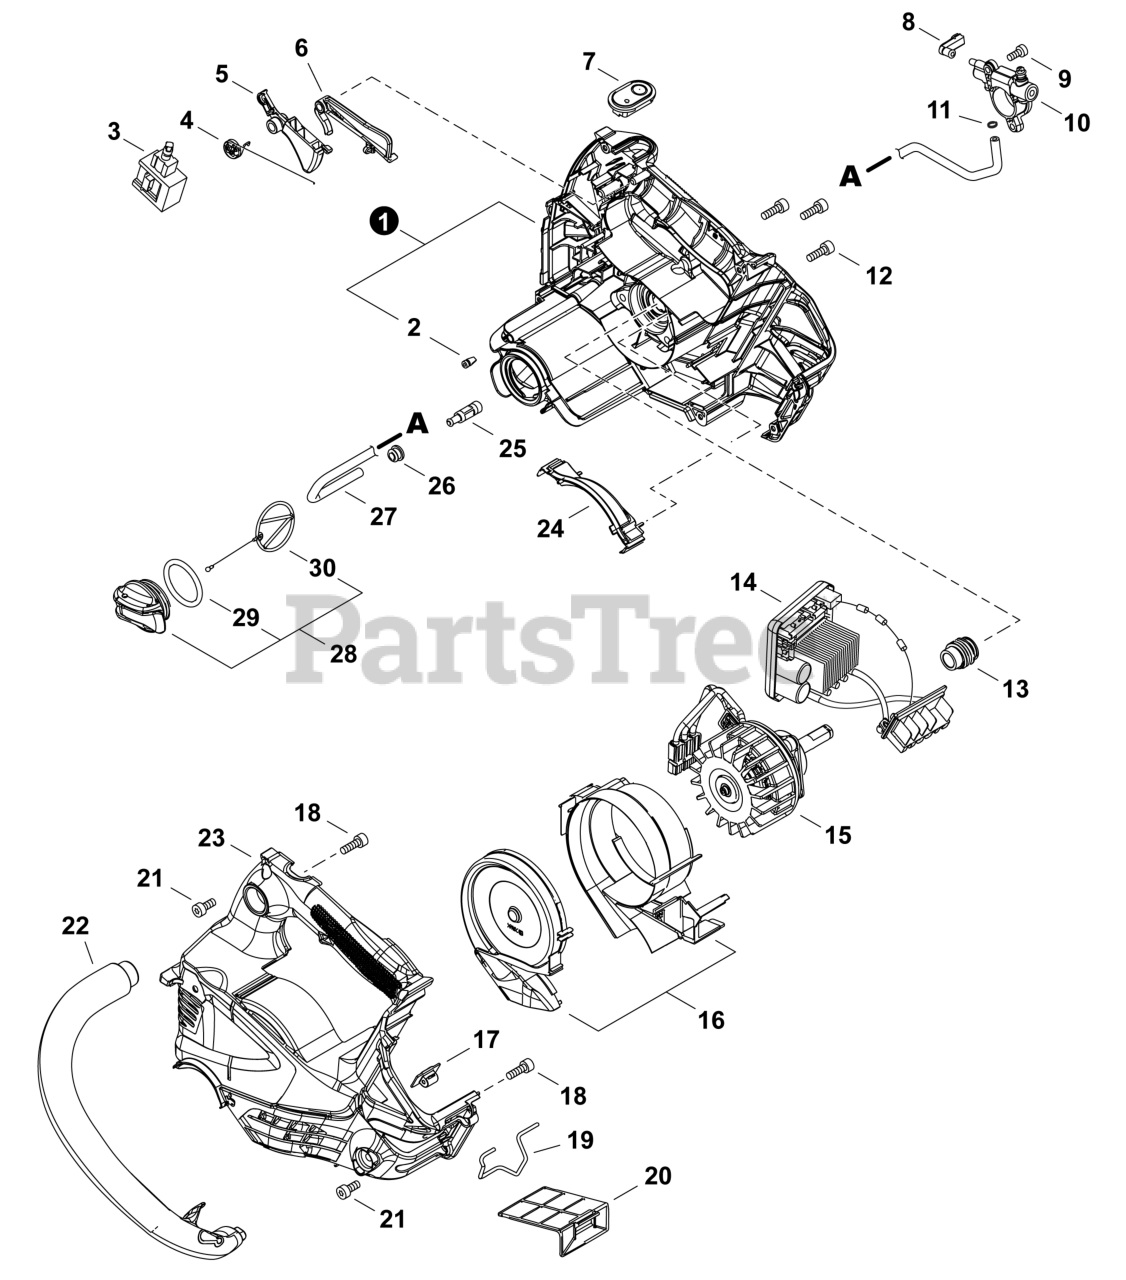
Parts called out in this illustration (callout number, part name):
1	HOUSING ASSY, MOTOR
2	VENT ASSY
3	SWITCH, SPEED CONTROL
4	SPRING, TORSION
5	TRIGGER
6	LOCKOUT, TRIGGER
7	SWITCH, ON-OFF
8	PIPE, OIL
9	BOLT, TORX 4x12
10	AUTO-OILER ASSY
11	CLIP 6.5 MM
12	BOLT, TORX 5x16
13	GEAR, WORM
14	CONTROL BOARD ASSY
15	MOTOR ASSY
16	FAN CASE ASSY
17	BRACKET, HARNESS
18	BOLT, TORX 5x16
19	RING, HARNESS
20	FILTER, AIR
21	BOLT, TORX 4x12
22	HANDLE, FRONT
23	COVER, MOTOR
24	COVER, MOTOR
25	FILTER ASSY, OIL
27	PIPE, OIL 3x6x200
28	CAP ASSY, OIL
29	O-RING 29
30	CONNECTOR, CAP L= 60 MM
